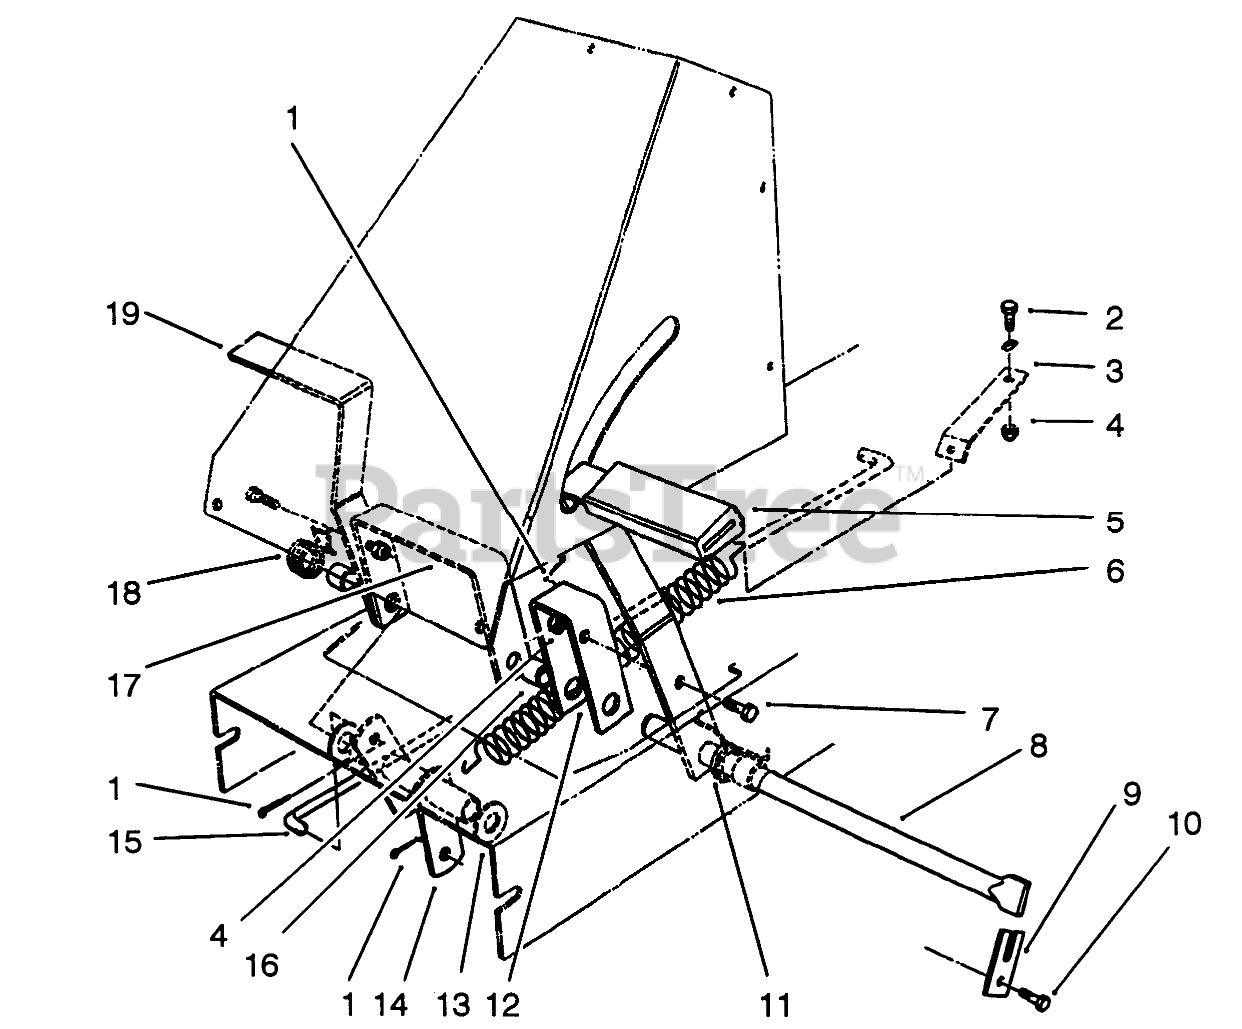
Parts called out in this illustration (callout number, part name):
1	PIN-COTTER
2	SCREW-HH
3	BRKT-SPRING RET
4	NUT-LOCK, NI
5	PAD-PEDAL
6	SPRING-EXTENSION
7	SCREW-HH
8	SHAFT-PEDAL PIVOT
9	RETAINER-SHAFT
10	SCREW-HH
11	SPRING-TORS CLUTCH
12	Bracket-Clutch Pedal
13	WASHER-FLAT
14	Pivot Tube
15	ROD-ENGAGE
16	SPACER-PEDAL
17	Bracket-Brake Pedal
18	SPRING-TORS BRAKE
19	Pedal
